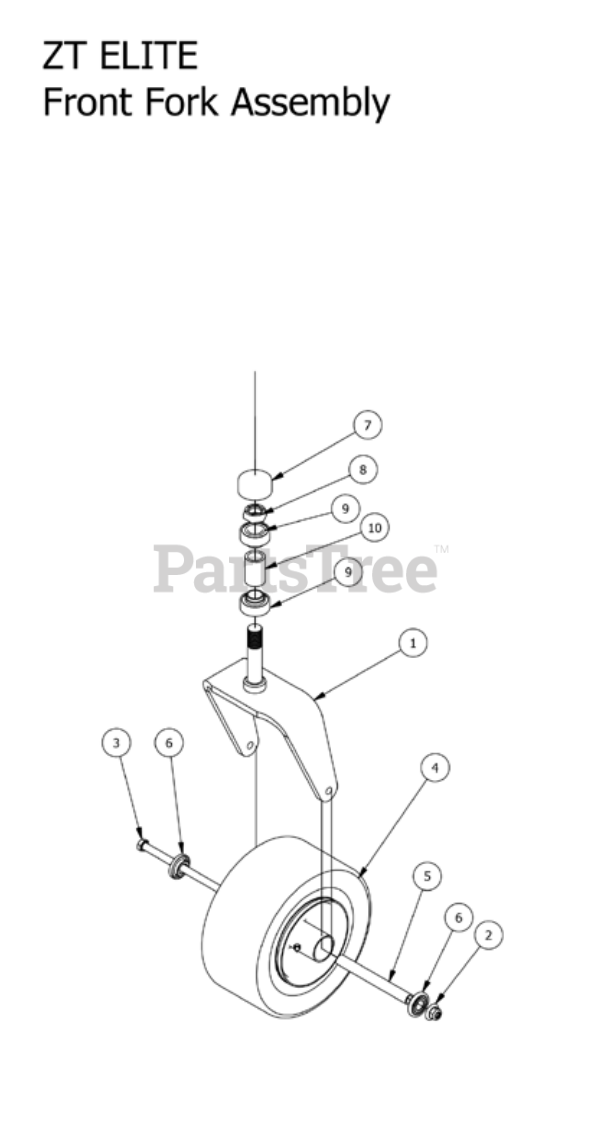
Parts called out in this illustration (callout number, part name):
1	Front Fork
2	1/2-13 Nylon Flange Nut-Orange
3	1/2" x 9" Bolt
4	Tire and wheel assembly
5	Front Wheel Spanner
6	Wheel Bearing
7	Rubber Bearing Cap
8	1" Fine Thread 1/2 Nut
9	Caster Bearing -MZ, 2009 & up
10	ZT/CZT Caster Bearing Spacer
